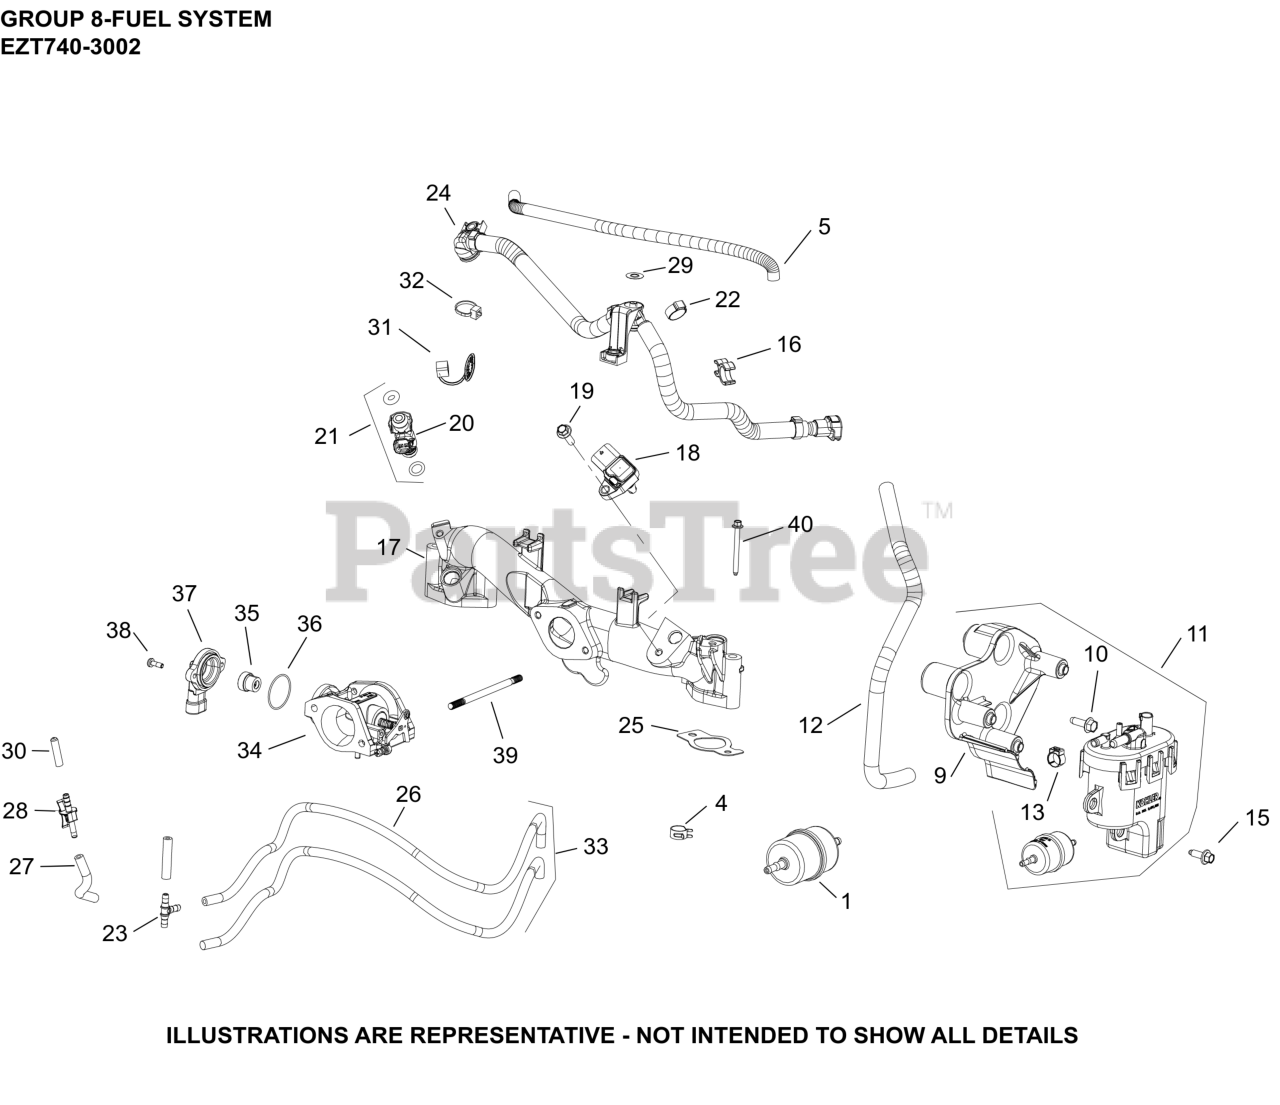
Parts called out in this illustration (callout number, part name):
1	FILTER, FUEL
4	SPRING CLAMP, HOSE
5	SLEEVE, ANTI-ABRASION
9	BAFFLE, FUEL MODULE
10	SCREW, THREAD FORMING
11	KIT, FUEL PUMP MODULE
12	SLEEVE, INSULATING
13	CLAMP, OETIKER
15	SCREW, HEX FLANGE (M6 W/DOG POINT)
16	RETAINER, CLIP
17	MANIFOLD MACHINED (EFI)
18	SENSOR, T-MAP
19	SCREW, FLG M6x1.0x20
20	INJECTOR, FUEL
21	KIT, FUEL INJECTOR O-RING
22	CLAMP, HOSE
23	TEE CONNECTOR
24	FUEL HOSE ASSY(ECV,FCV,EZT,EKT,PCH,PCV)
25	KIT, INTAKE MANIFOLD GASKET
26	HOSE, EVAPORATIVE 20"- (#24326143S)
27	HOSE EVAPORATIVE (WALBRO)
28	CONNECTOR, EVAPORATIVE
29	CLIP, RETAINER
30	CAP, MASKING
31	CAP, CONNECTOR
32	TIE, CABLE
33	HOSE, ASSEMBLY
34	BODY ASSEMBLY, THROTTLE W/TPS & TS
35	MAGNET, TPS SENSOR
36	O-RING, TPS SENSOR
37	SENSOR, THROTTLE POSITION
39	STUD-USE 25 072 48-S
40	SCREW, HEX FLANGE (M6 W/DOG POINT)
49	PUMP, FUEL (PULSE)
NI	SCREW, HEX HEAD
NI	SLEEVE, ANTI ABRASION
